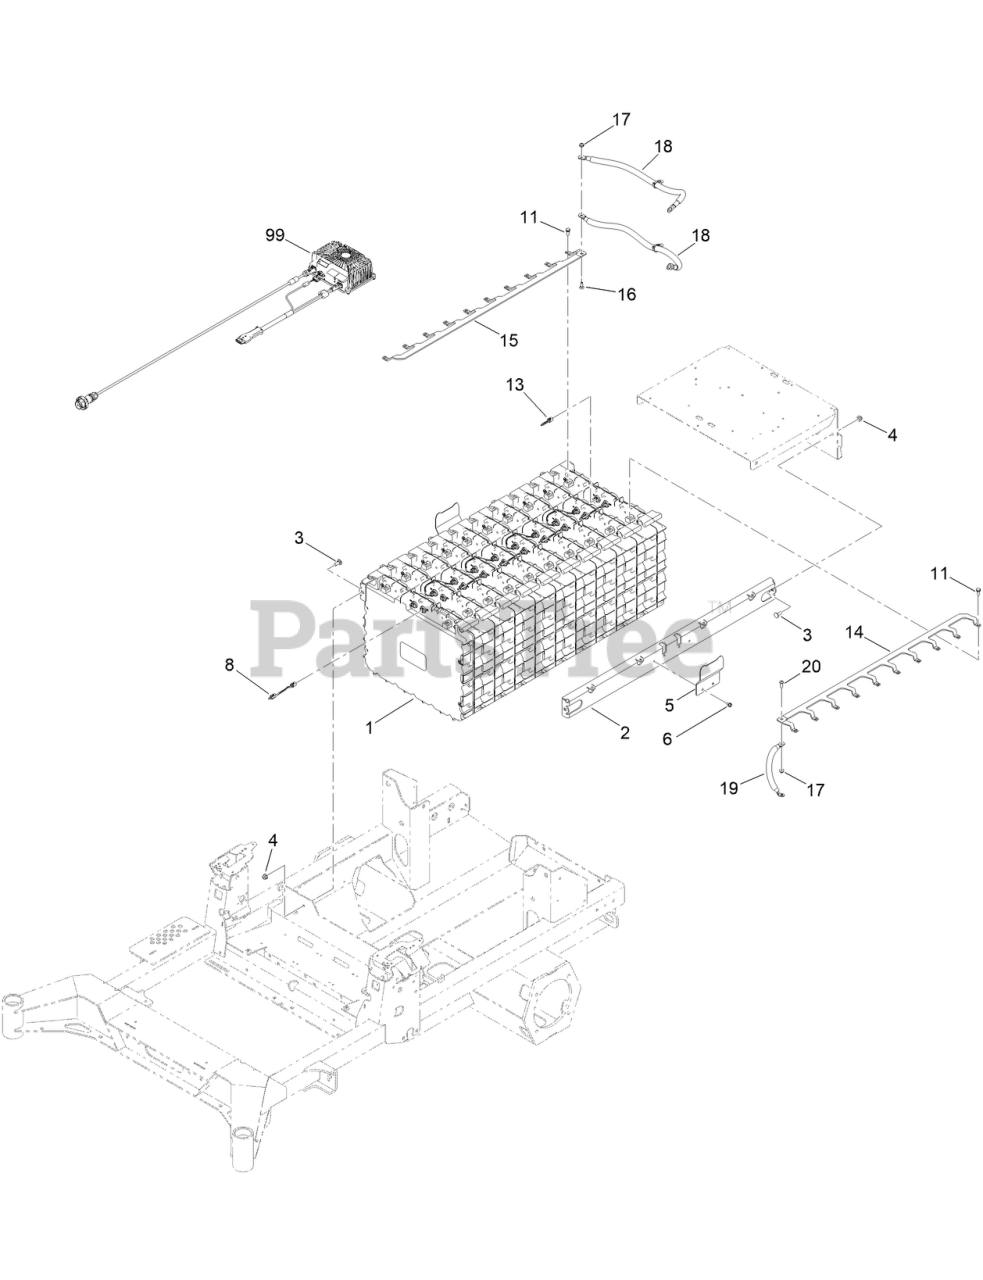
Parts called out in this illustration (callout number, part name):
1	BATTERY ASM
2	PLATE-RETAINER
3	SCREW-CARR
4	NUT-HF, NI
5	PLATE-COVER
6	SCREW-HWH
8	HARNESS-WIRE, DATA INTERFACE
11	SCREW-SEMS
13	HARNESS-WIRE, CAN TERMINATOR
14	BUSBAR-10, BK
15	BUSBAR-10, RD
16	BOLT-CARR
17	NUT-HF
18	CABLE-BATTERY, RD ASM
19	CABLE-BATTERY, BK ASM
20	SCREW-PH
99	CHARGER-3300W
